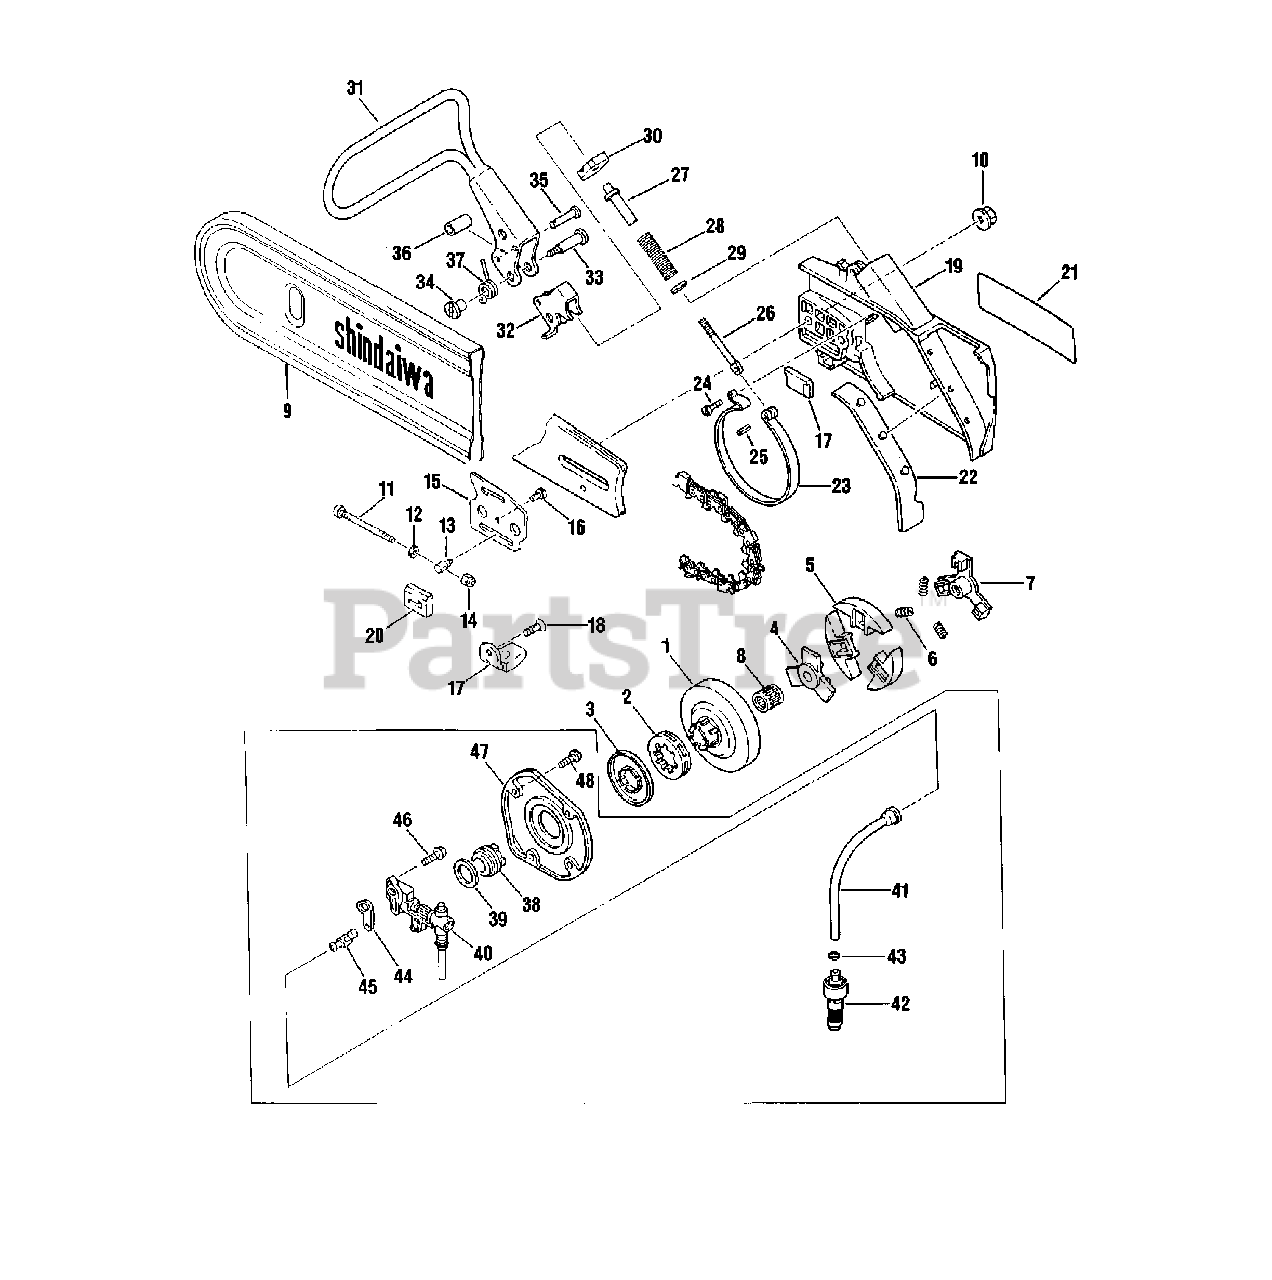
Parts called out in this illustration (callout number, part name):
1	DRUM, CLUTCH
2	SPROCKET, RIM
3	COVER, RIM
4	HUB, CLUTCH - INNER
5	SHOE, CLUTCH
6	SPRING, CLUTCH
7	HUB, CLUTCH - INNER
8	BEARING, NEEDLE
9	PROTECTOR
10	NUT
11	BAR ADJUSTING SCREW
12	WASHER - 5
13	TENSIONER, CHAIN
14	LOCKNUT
15	MOUNT GUARD
16	SCREW - 4X10
17	CATCHER, CHAIN
18	SCREW - 5X12
19	CLUTCH COVER ASSY
20	GUIDE, CHAIN
21	NAME PLATE (C)
22	PROTECTOR
23	BAND, BRAKE
24	BAND BOLT
25	PIN
26	ROD, ADJUST
27	SCREW, ADJUST
28	SPRING, BRAKE
29	WASHER
30	BLOCK
31	LEVER, BRAKE
32	LEVER - INNER
33	BOLT, LEVER, USE 22161-54580
34	NUT
35	PIN - STOPPER
36	CUSHION
37	SPRING
38	GEAR
39	PLATE, THRUST
40	OIL PUMP ASSY
41	TUBE, OIL
42	FILTER, OIL
43	CLIP
44	GASKET, PUMP
46	SCREW - 4X16
47	COVER, PUMP
48	SCREW - 4X10
